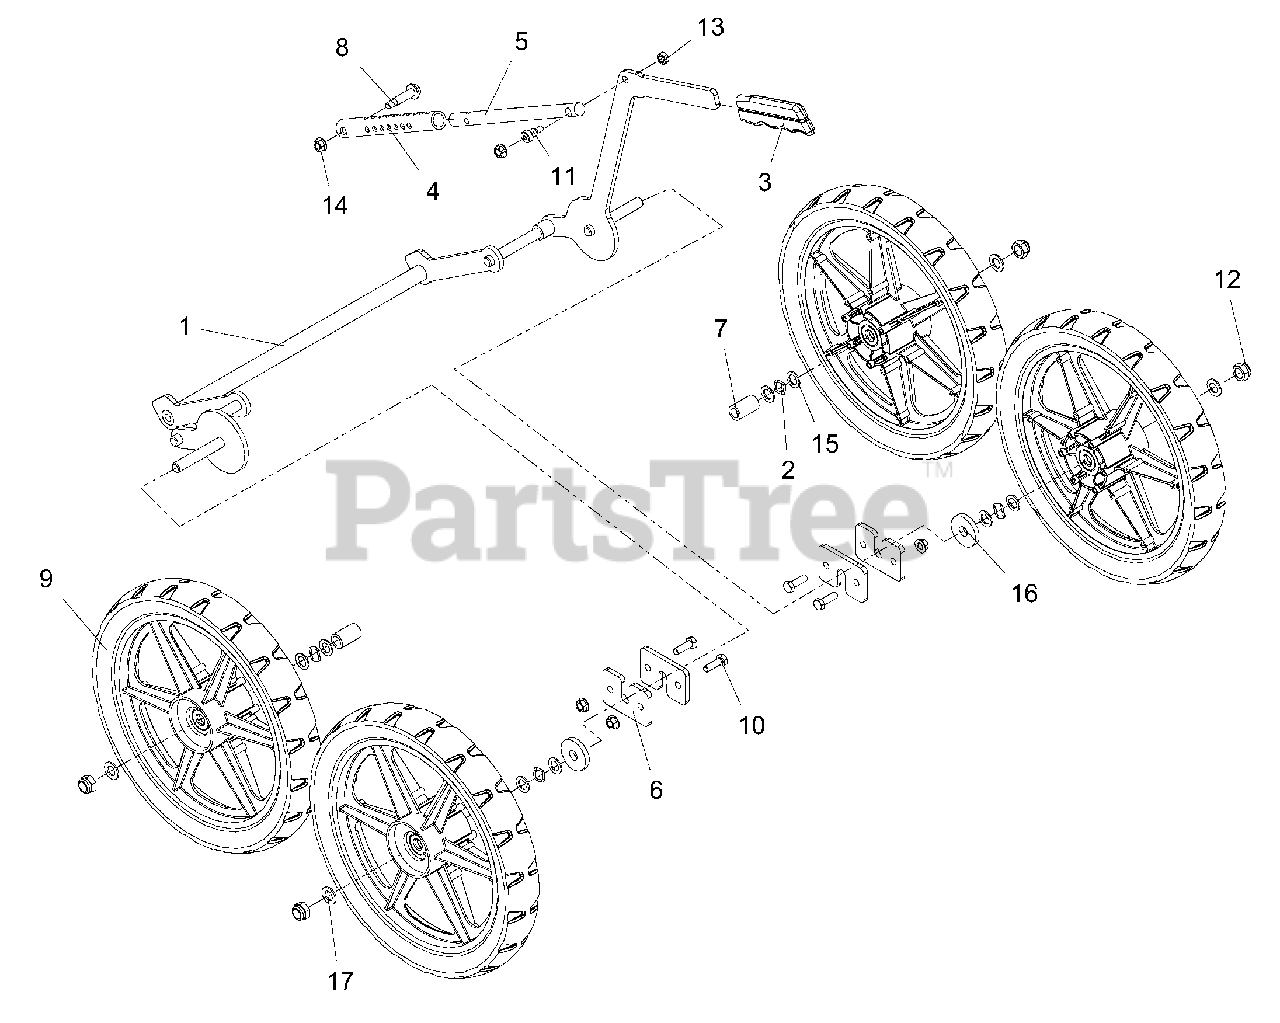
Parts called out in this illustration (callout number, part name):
1	WLDMT, CROSS SHFT - HEIGHT ADJ
2	WAVE WASHER .531X.781X.125FH
3	GRIP, PARKING BRAKE (YELLOW)
4	TUBE, ADJ - APV HEIGHT ADJ
5	ROD, ADJ - APV HEIGHT ADJ
6	PLATE, RETAINER-APV HEIGHT ADJ
7	SPCR, WHEEL - APV REAR WHEEL
8	BLT-SHLDR, .50X1.15X.312-18GR5
9	WHEEL-14X2 .50ID W/DRIVE HUB
10	@BLT-HEX .31-18X1.00 GR5 YWZC
11	BLT,SHLDR-.38DIA X.75EL;.31-18
12	NUT, ACORN - 1/2-13 ELC
13	@NUT-LK-CTR .31-18 YWZC
14	@NUT-LK-TOP-FLG .31-18 YWZC
15	WSHR-FL-STL .52X.827X.062 YWZC
16	WSHR-FL-STL .515X1.625X.250 YZ
17	WSHR-FL-STL .505X.880X.072 YWZ
